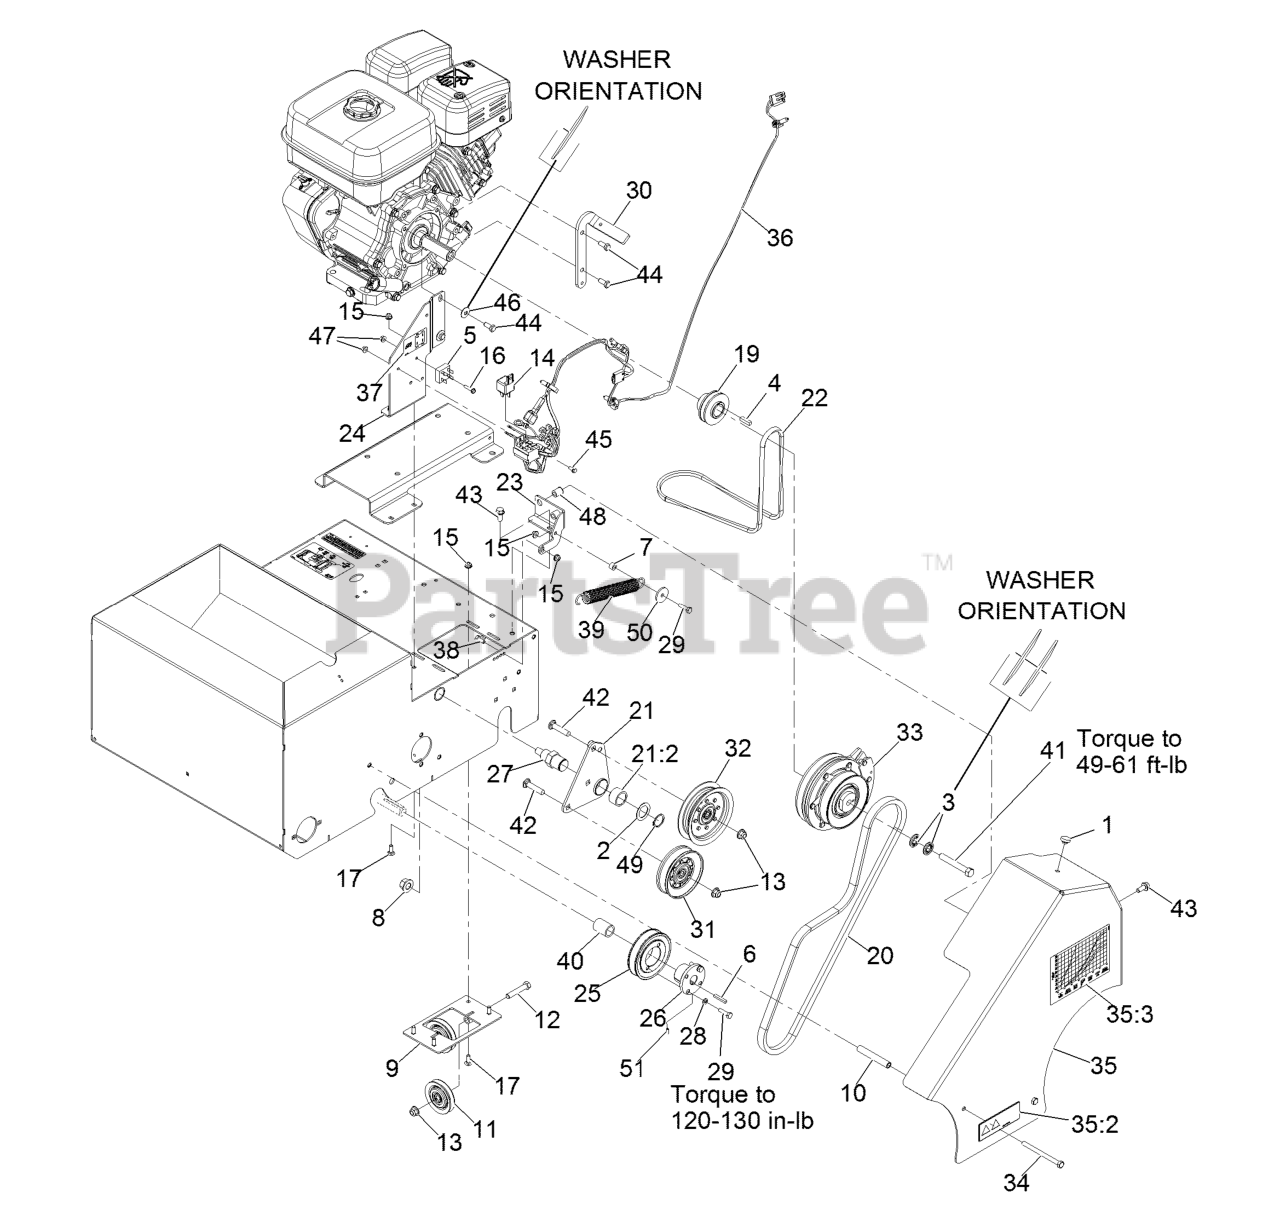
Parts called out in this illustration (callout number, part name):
2	WASHER-SPACER
3	WASHER-SPRING
5	RECTIFIER-BRIDGE
6	KEY-SQUARE
8	Nut-Lock 1/2-13
9	PULLEY-TENSION
10	SPACER-KICKSTAND, LONG
11	PULLEY-IDLER
12	SCREW-HH
13	NUT-HF, NI
16	SCREW-HWH
17	BOLT-CARR
19	PULLEY-MULE DRIVE
20	BELT-SEEDER, CLUTCH
21	IDLER ARM ASM
21:2	BUSHING
22	BELT-MULE DRIVE
23	BRACKET-SPRING
24	SUPPORT-ENGINE
26	BUSHING-TAPER LOCK
27	PIVOT-IDLER
28	SCREW-HH
29	SCREW-HH
30	STOP-CLUTCH
31	PULLEY-IDLER V
32	PULLEY-IDLER FLAT (4.06-I
33	CLUTCH-ELECTRIC
34	SCREW-HH
35	BELT GUARD ASM
35:2	DECAL-DANGER
35:3	DECAL-GRAPH, SEED
36	HARNESS-SLICER/SEEDER
37	Decal-Bridge Rectifier
38	SCREW-HH
39	SPRING-EXTENSION
41	SCREW-HH
42	SCREW-CARR
43	SCREW-HHF
44	SCREW-HH
45	SCREW-HWH
46	WASHER-BELLEVILLE
47	NUT-LOCK, FLANGE
48	NUT-CLINCH
49	RING-RETAINING
50	WASHER
51	SCREW-SET, HS
